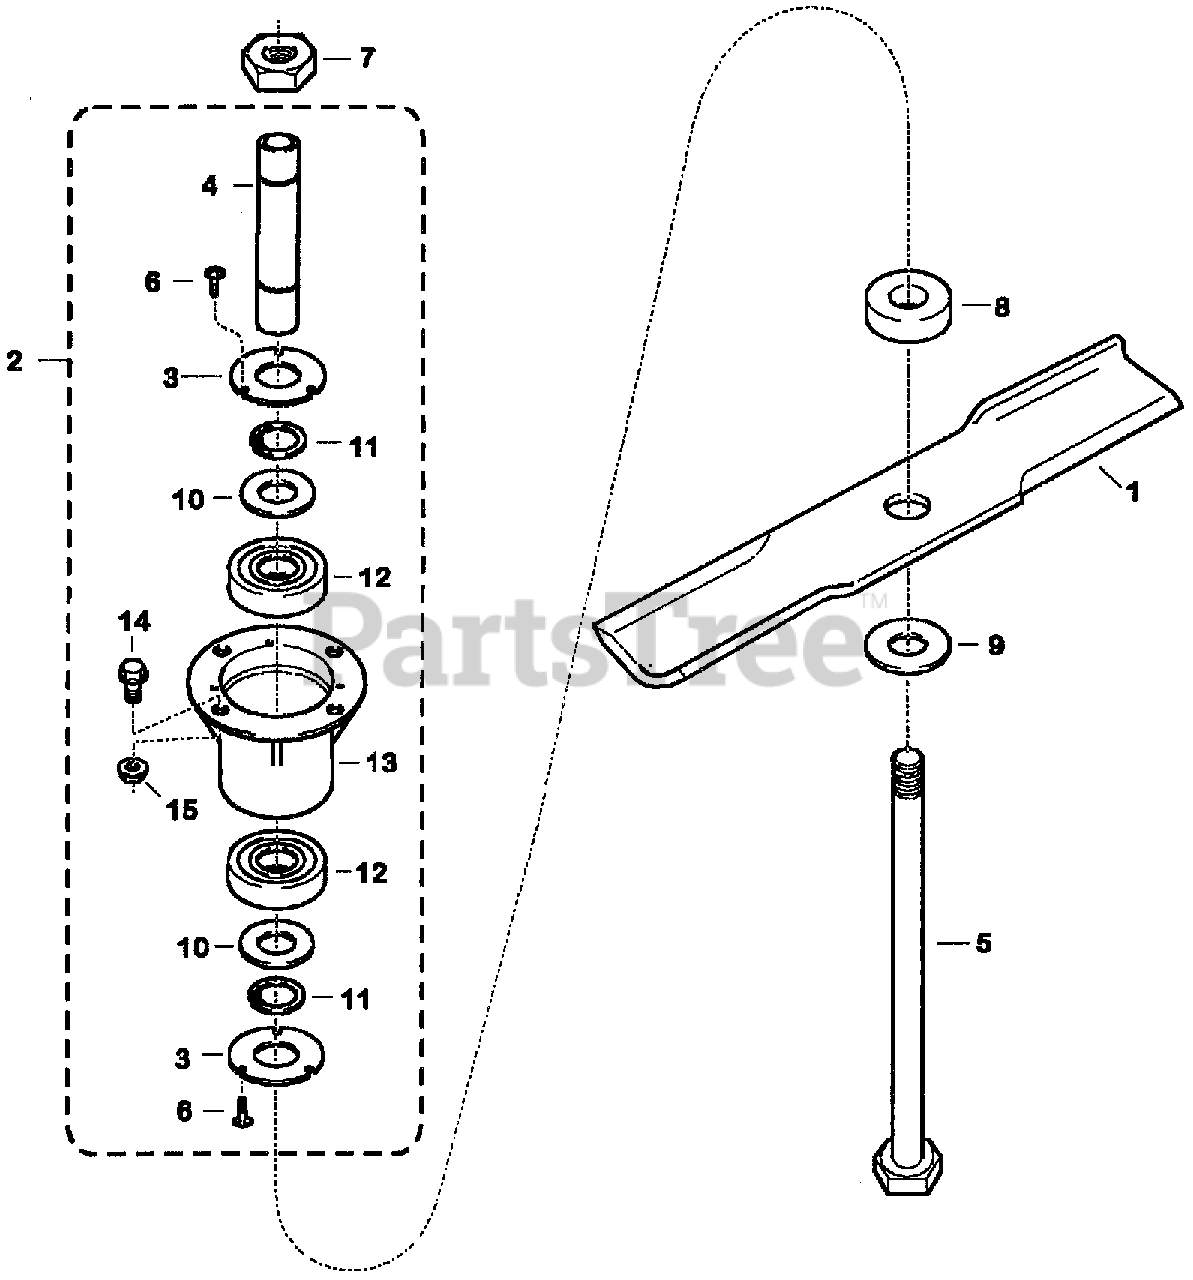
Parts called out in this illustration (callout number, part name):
1	BLADE, HIGH LIFT (21")
2	HOUSING ASSY., BLADE BEARING
3	CAP, BEARING HOUSING
4	SHAFT, BLADE
5	BOLT, BLADE
6	SCREW, BEARING HOUSING (10-32-1/2)
7	JAM NUT (5/8"-18)
8	COLLAR, BLADE (1/2")
9	WASHER, BLADE
10	WASHER, SLINGER
11	RING, SNAP
12	BEARING, BLADE SHAFT
